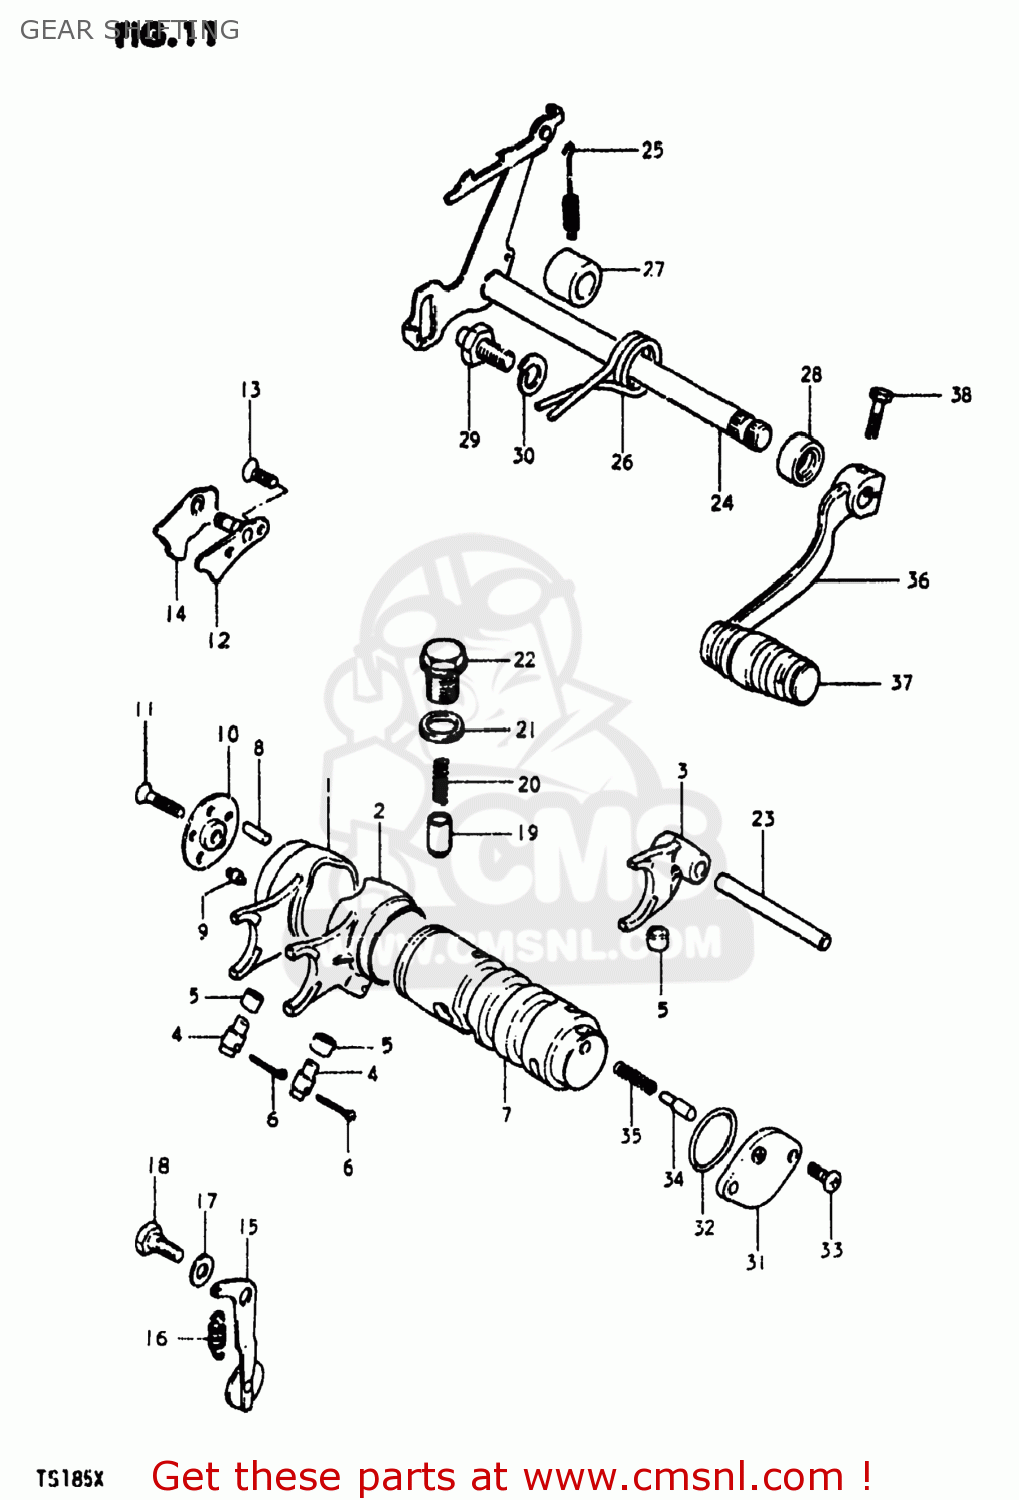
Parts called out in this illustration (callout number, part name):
1	FORK,GEAR SHIFT NO.1
2	FORK,GEAR SHIFT NO.2
3	FORK,GEAR SHIFT NO.3
4	PIN
5	SPACER(6X9.8X6)
6	PIN 25X20
7	CAM,GEAR SHIFT
8	ROLLER(4X13.8)
9	PIN
10	RETAINER,GEAR SHIFT CAM DR PIN
11	SCREW
12	GUIDE,GEAR SHIFT CAM
13	SCREW
14	PAWL,GEAR SHIFT CAM STOPPER
15	STOPPER,GEAR SHIFT CAM
16	SPRING
17	WASHER(6.5X16X2.3)
18	BOLT(6X16.1)
19	STOPPER,GEAR SHIFTING
20	SPRING
21	GASKET(14X19.2X2) (NAS)
22	BOLT,GEAR SHAFT CAM STOPPER
23	SHAFT,GEAR SHIFT FORK
24	SHAFT,GEAR SHIFT
25	SPRING
26	SPRING
27	SPACER(12X20X15.3)
28	OIL SEAL
29	STOPPER,GEAR SHIFT ARM
30	WASHER
31	BODY,GEAR SHIFT SWITCH
32	O-RING (D:2.4 ID:26.2)
33	SCREW
34	PIN(5X15.5)
35	SPRING
36	LEVER ASSY,GEAR SHIFT
37	RUBBER,GEAR SHIFT PEDAL
38	BOLT
